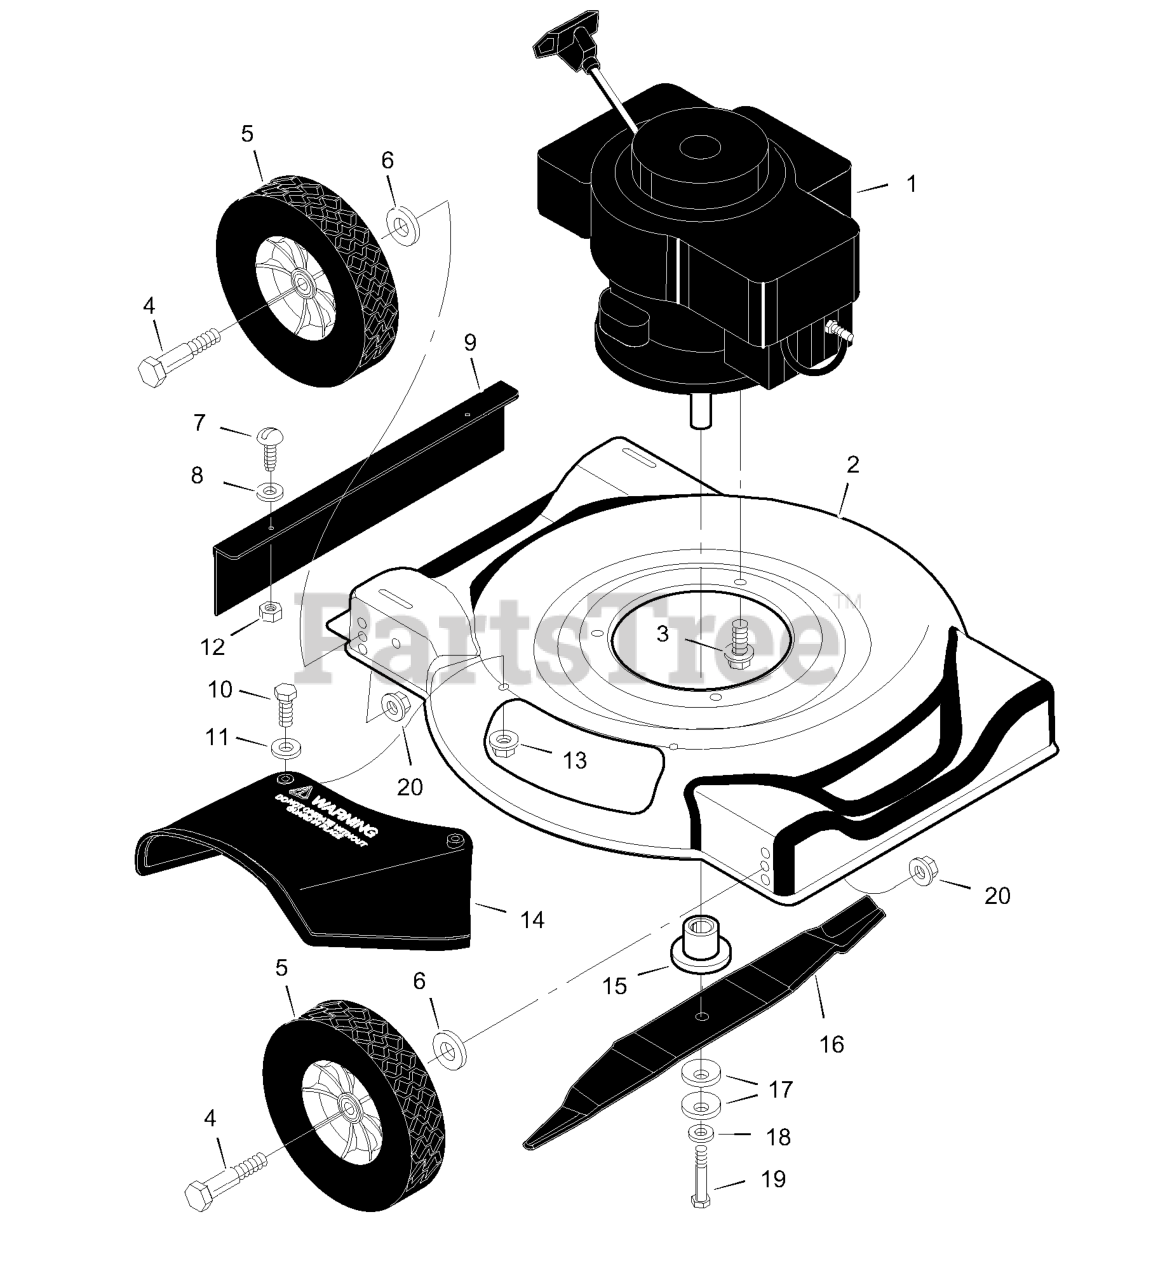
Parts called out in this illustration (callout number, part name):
1	Engine
2	Housing
3	Bolt, Engine
4	Bolt, Axle
5	Wheel and Tire
9	Deflector, Rear
11	Washer
13	Locknut
14	Deflector, Chute
15	Blade Adapter
16	Blade - 20"
17	Washer, Blade
20	Locknut
